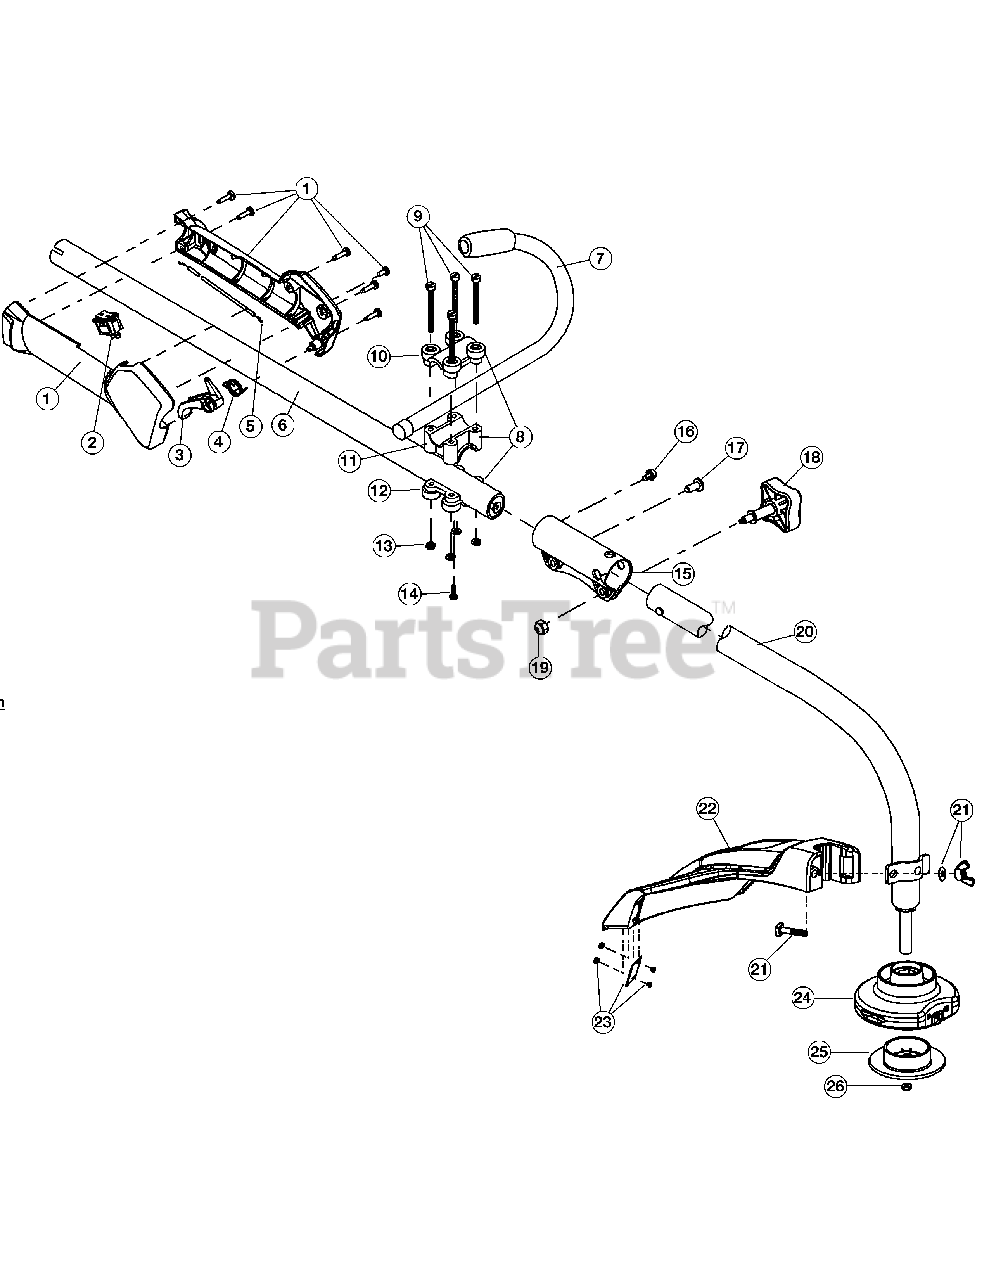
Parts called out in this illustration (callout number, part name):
1	Throttle Housing Assembly (Incl. Ref No. 2-4)
3	Throttle Trigger
4	Throttle Trigger Spring
5	Throttle Cable
6	Upper Drive Shaft Housing Assembly
7	J-Handle Assembly
8	Handle Bracket Assembly (Incl. Ref No. 9-14)
10	Upper Handle Clamp
11	Middle Handle Clamp
12	Lower Handle Clamp
14	Anti-Rotation Screw
15	Split Boom Coupler (Incl. Ref No. 16-19)
18	Adjustment Knob
19	Knob Retaining Nut
20	Lower Drive Shaft Housing Assembly
21	Guard Mounting Hardware
22	Guard Assembly (Incl. Ref No. 23)
23	Blade Assembly
24	Fixe Line Head Assembly (Incl. Ref No. 25 & 26)
25	Glide Cap
26	Locknut
